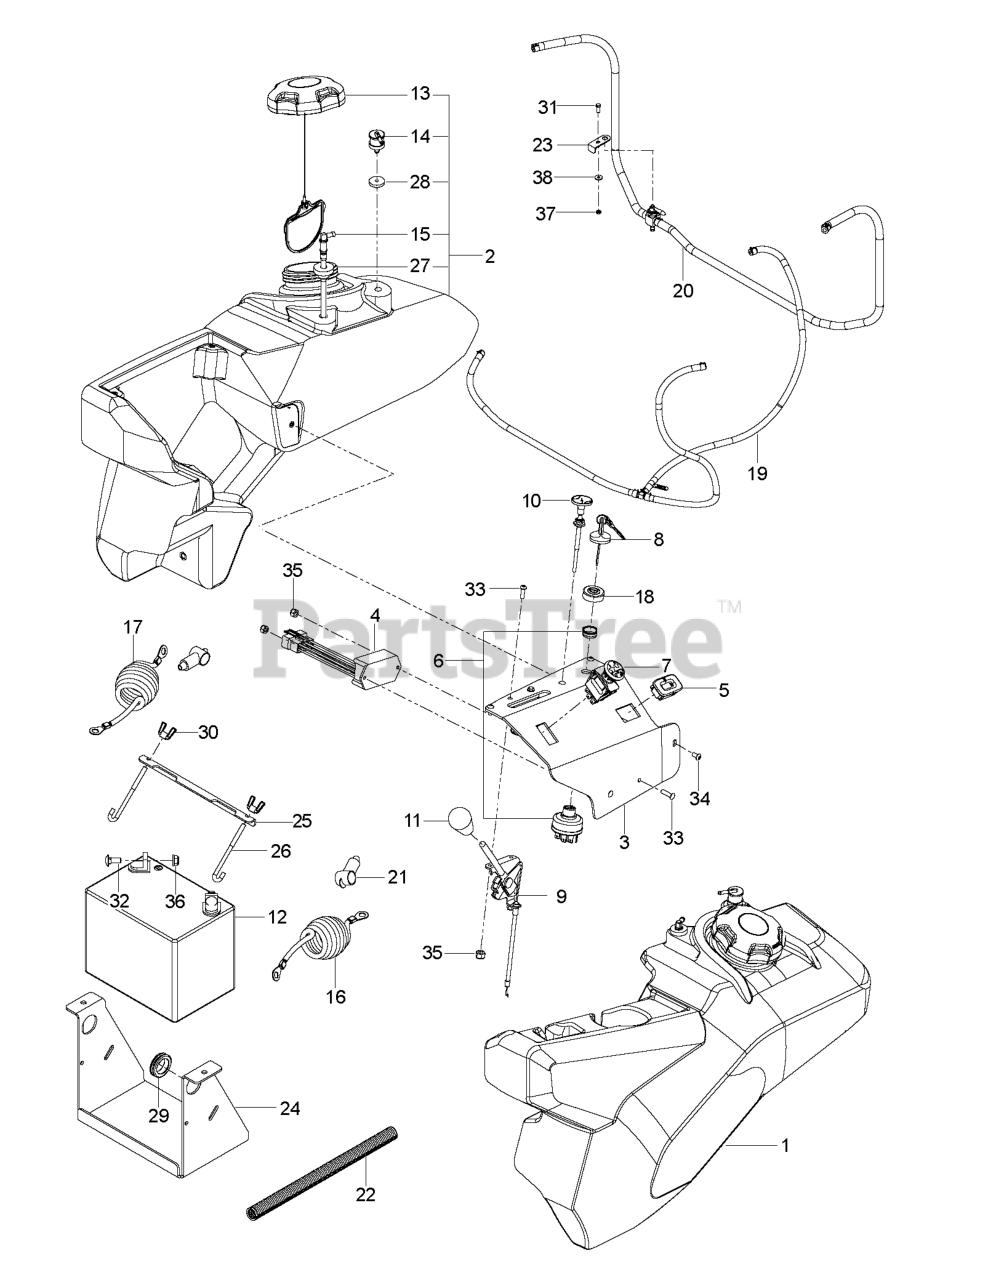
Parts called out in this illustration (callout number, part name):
1	FUEL TANK LH PZ GRAY
2	FUEL TANK ASM RH GRAY PZ
3	PANEL.CONTROL.GAS.GRAY
4	TIMER, SEAT
5	GUAGE.SRVCMNDR.HRMTR.
6	SWITCH, IGNITION, INDAK
7	SWITCH, PTO 10 AMP
8	KEY, IGNITION
9	CABLE, THROTTLE, 46"
10	CABLE, CHOKE, 48"
11	KNOB - SHIFT
12	BATTERY, 12 V 330 AMP
13	CAP, FUEL
14	VALVE.FUEL.CHECK
15	FITTING, FUEL
16	CABLE, POSITIVE, 55"
17	CABLE, NEG, 55"
18	CAP IGNITION NUT
20	ASSEMBLY, FUEL LINE
22	LOOM, SPLIT, CONVOLUTED
23	BRACKET,FUEL VALVE, BLACK
24	BRACKET, BATTERY, BLK
25	BRACKET, BATTERY MOUNT
27	RUBBER GROMMET
28	GROMMET, CHECK VALVE
29	RUBBER GROMMET
30	WING NUT 1/4
31	HCS 1/4C X 3/4 HCS
32	RP BOLT 5/16-18 X3/4 ZN/YEL GR
33	SCR #10-24 X .75 SKT HD BLK
34	SCR #10-24 X 3/8 SKT HD BLK OX
35	NUT 10-24 NYLOC
36	5/16-18 NYLOC FLANGE NUT
37	JAM NUT 1/4C (2 2 PW01)
38	SCR #10-24 X .75 SKT HD BLK
38	WASHER 1/4 FLAT
